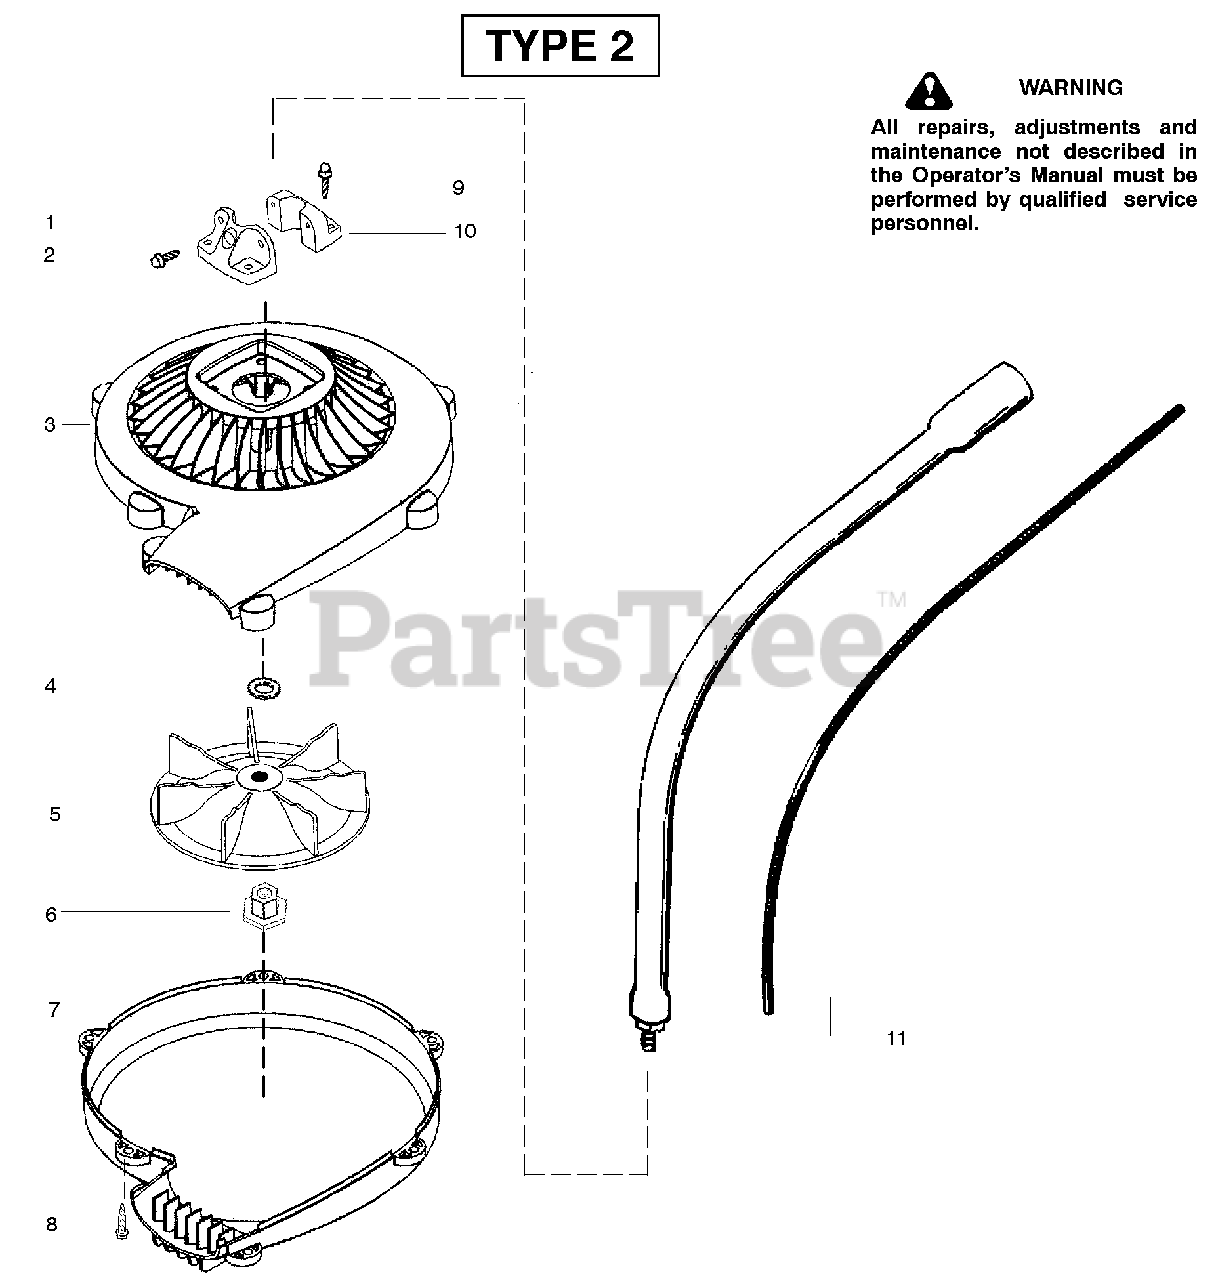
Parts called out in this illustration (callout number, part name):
3	Hsg.-Blower (upper)
6	Arbor-Impeller
7	Hsg.-Blower (lower)
11	Kit-Lower Driveshaft
